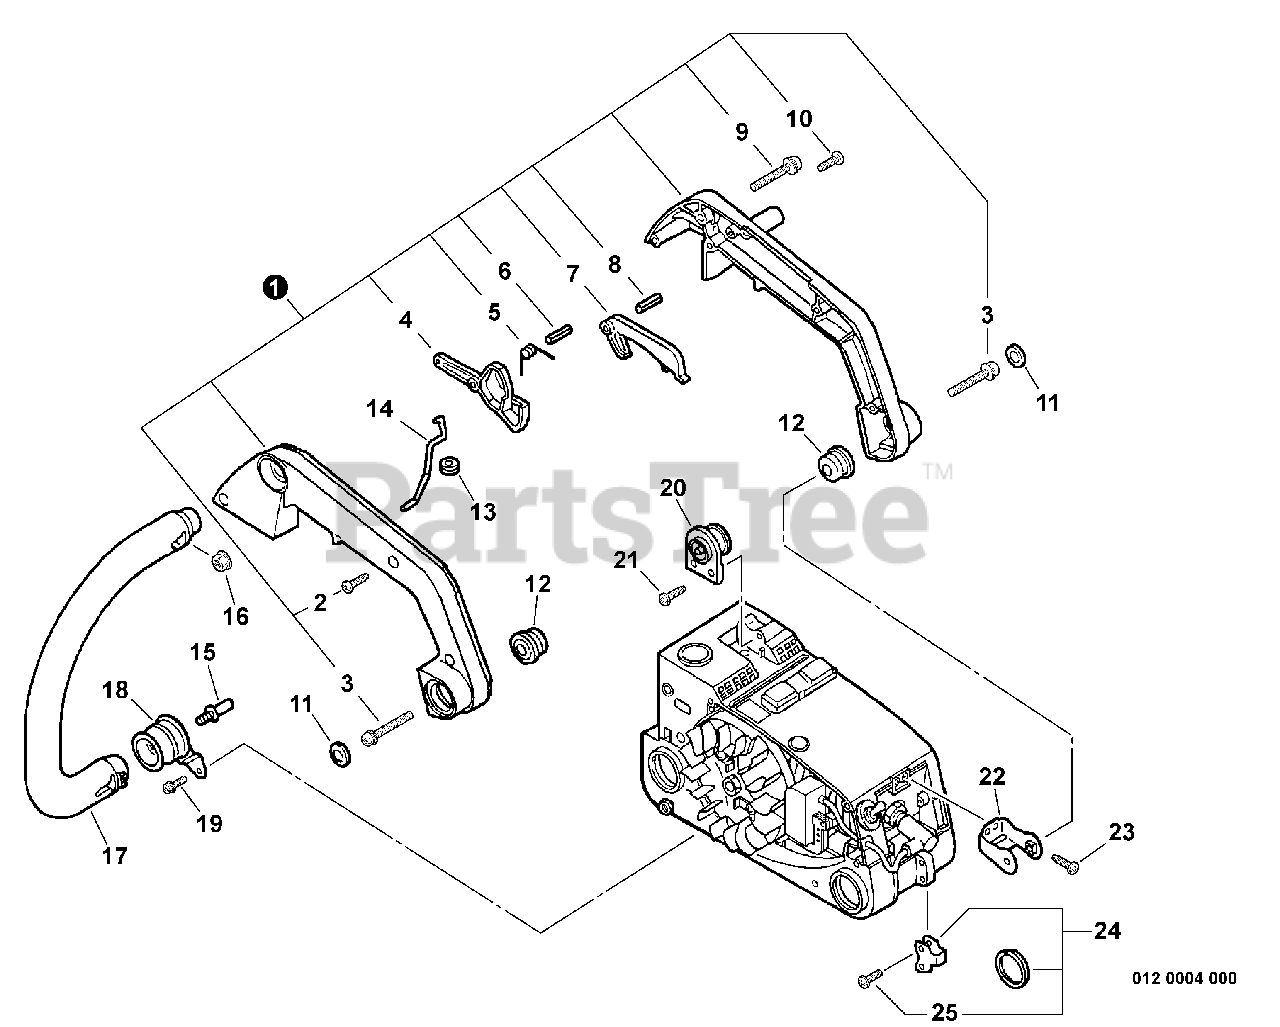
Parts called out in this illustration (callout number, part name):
1	HANDLE ASSY - REAR
2	SCREW - 4X16
3	SCREW - 4X10
4	TRIGGER, THROTTLE
5	SPRING, TRIGGER
6	PIN - SPRING -- 4X25
7	LOCKOUT, THROTTLE
8	PIN - SPRING -- 4X20
9	SCREW - 5X35
10	SCREW - 5X14
11	CAP, CUSHION
14	ROD, THROTTLE
16	NUT - 5 -- FLANGE
17	HANDLE - FRONT
19	SCREW - 4X16
21	SCREW - 4X14
22	BRACKET, HANDLE
23	SCREW - 4X14
24	HANGER KIT
25	SCREW - 4X16
